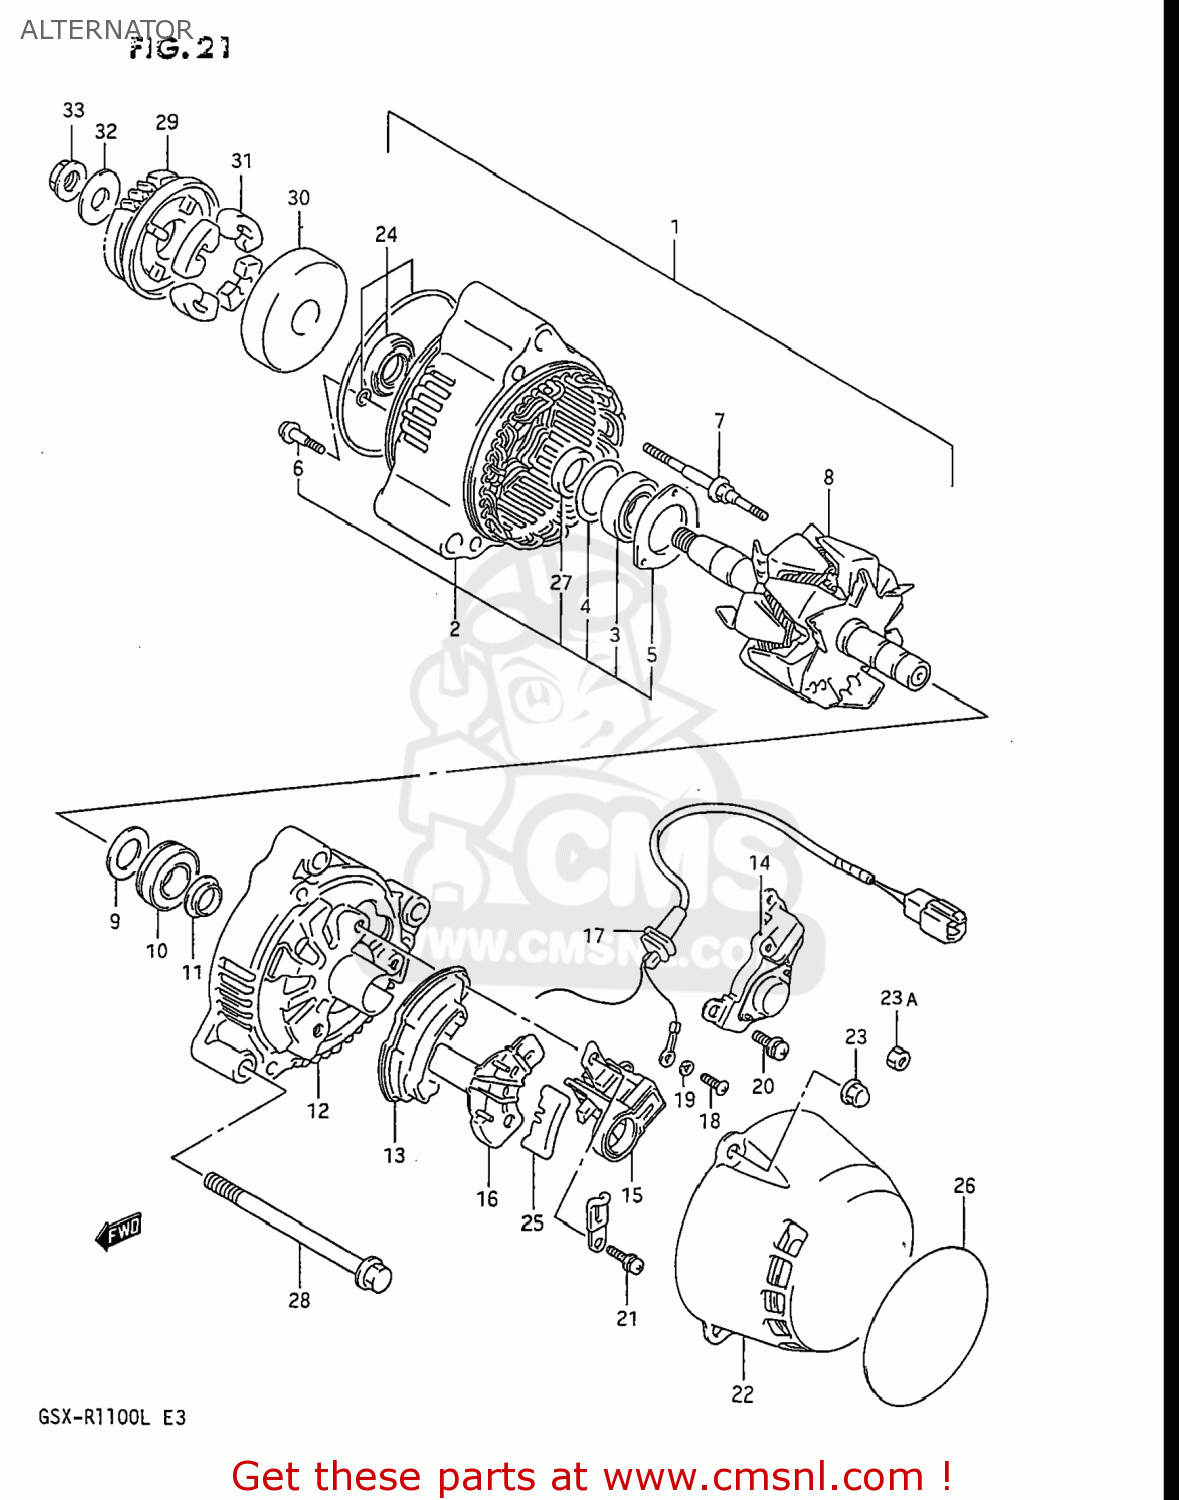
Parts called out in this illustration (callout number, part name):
1	GENERATOR ASSEMBLY
2	FRAME,DRIVE END
3	BEARING
4	COVER,BEARING
5	RETAINER
6	SCREW,BEARING RETAINER
7	STUD BOLT
8	ROTOR ASSEMBLY
9	COVER (2)
10	BEARING
11	COVER(2)
12	FRAME,END
13	HOLDER,RECTIFIER
14	REGULATOR
15	HOLDER,BRUSH
16	COVER,RECTIFIER
17	WIRE,LEAD
18	SCREW
19	LOCK WASHER
20	SCREW
21	SCREW
22	COVER
23	NUT
23A	NUT ,5MM
24	SEAL SET,OIL
25	BUSH
26	PROTECTOR,ALTERNATOR
27	SPACER
28	BOLT 8X90
29	GEAR,GENERATOR DRIVEN
30	HOUSING,GENERATOR GEAR
31	DAMPER,GENERATOR DRIVEN
32	WASHER
33	NUT
